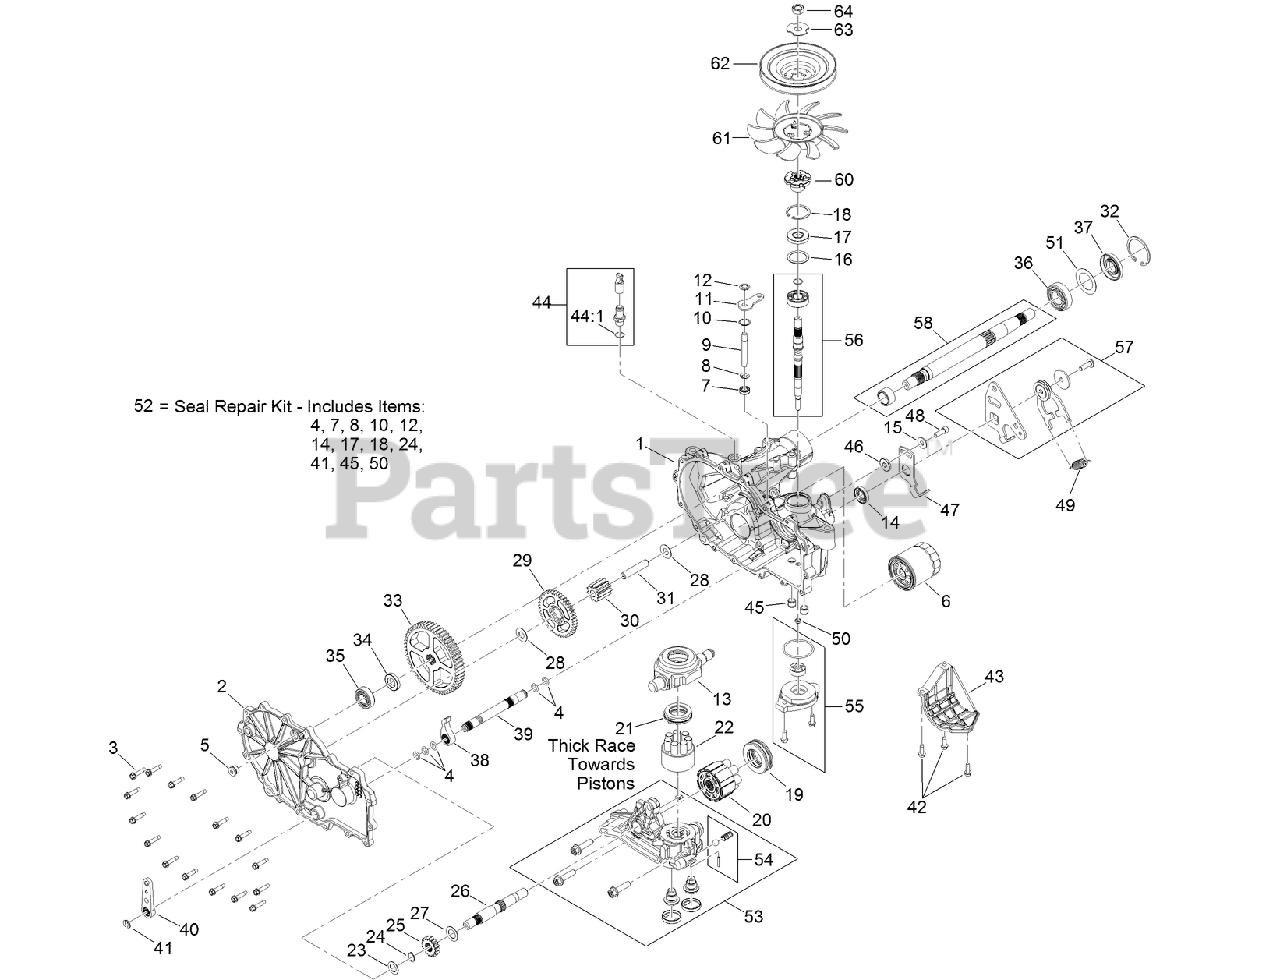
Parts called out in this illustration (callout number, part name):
1	LH MAIN HOUSING KIT
2	LH SIDE COVER KIT
3	SCREW-HHF
4	O-RING
5	PLUG-STRAIGHT
6	ELEMENT-OIL FILTER, HYD
7	SEAL-LIP
8	RING-RETAINING, EXTERNAL
9	ROD-BYPASS
10	RING-RETAINING, INTERNAL
11	Arm-Bypass
12	RING-RETAINING, EXTERNAL
13	SWASHPLATE-TRUNNION
14	SEAL-LIP
15	WASHER
16	SPACER
17	SEAL-LIP
18	RING-RETAINING
19	Bearing-Thrust
20	MOTOR CYLINDER BLOCK KIT
21	BEARING-THRUST
22	PUMP BLOCK ASM
23	WASHER-FLAT
24	RING-RETAINING
25	GEAR-16T
26	SHAFT-MOTOR
27	WASHER
28	WASHER
29	GEAR-43T
30	GEAR-11T
31	PIN-JACKSHAFT
32	RING-RETAINING
33	GEAR-54T
34	SPACER
35	BEARING-BALL
36	BEARING-BALL
38	PAWL-BRAKE
39	SHAFT-BRAKE, INBOARD
40	HANDLE-BRAKE
41	RING-RETAINING, EXT
43	GUARD-FILTER, LH
44	ADAPTER-STRAIGHT
44:1	O-RING
45	TUBE-CONNECTING
46	SPACER
47	ARM-NEUTRAL, LEFT
48	Screw-Sh
49	SPRING-EXTENSION
50	SEAL-GEROTOR
51	SPACER
52	SEAL KIT
53	LH CENTER SECTION CHARGE KIT
54	CHARGE RELIEF KIT
55	CHARGE KIT
56	INPUT SHAFT KIT
57	CONTROL ARM KIT
58	AXLE SHAFT KIT
60	HUB-PULLEY
62	PULLEY
63	WASHER-SLOTTED
64	NUT-HJ
